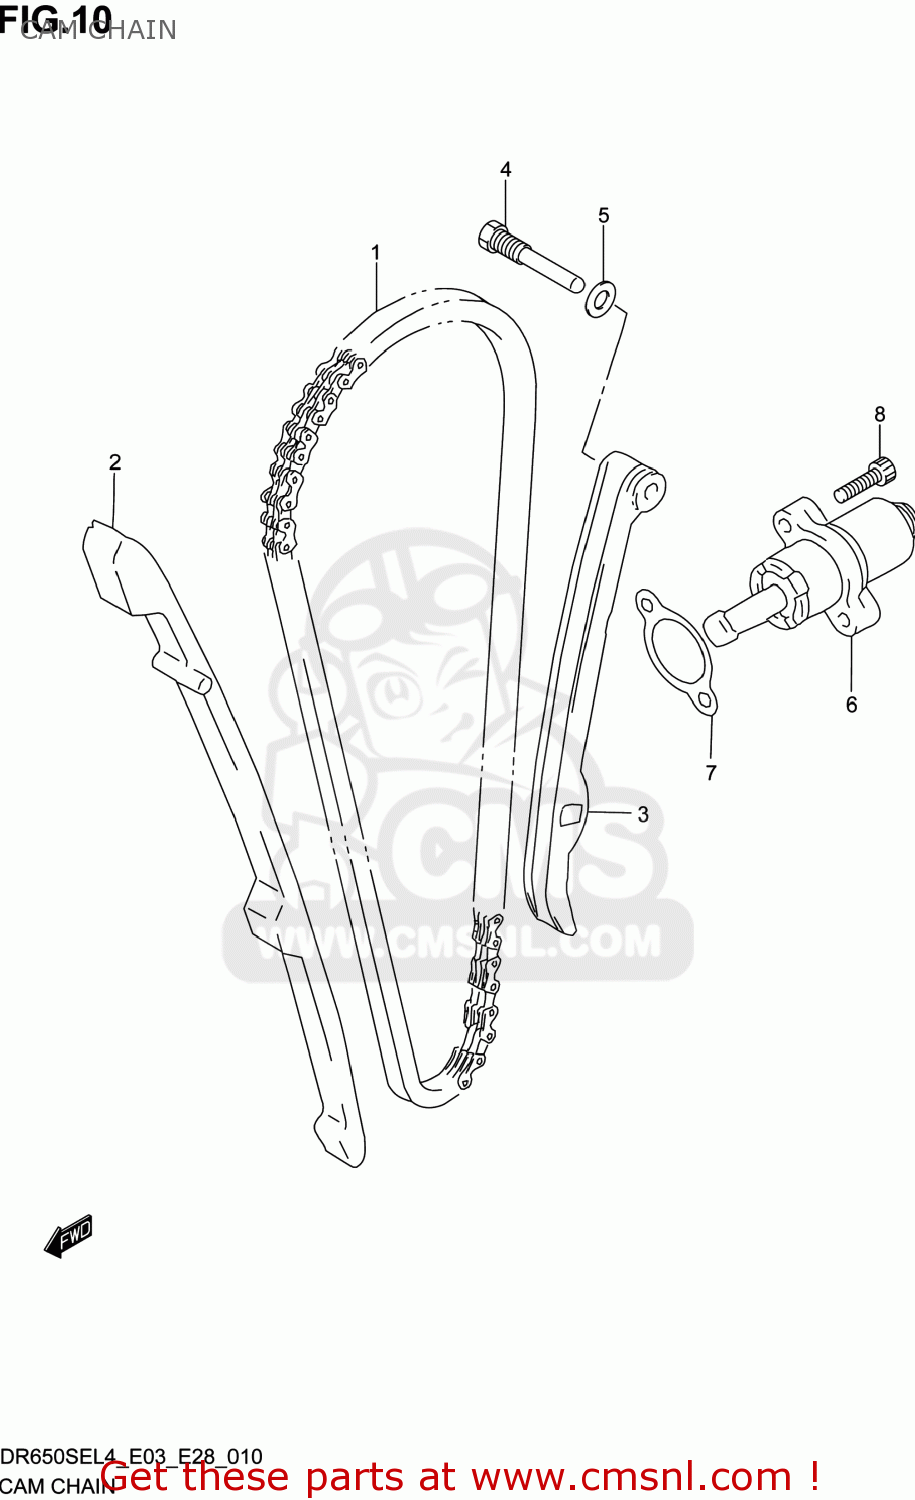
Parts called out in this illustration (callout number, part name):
1	CHAIN,CAMSHAFT DRIVE
2	GUIDE,CAM CHAIN
3	TENSIONER,CAM CHAIN
4	BOLT,CAM CHAIN TENSIONER
5	GASKET(8.2X14X1) (NAS)
6	ADJUSTER ASSY,TENSIONER
7	GASKET,TENSIONER ADJUSTER (NAS)
8	BOLT
